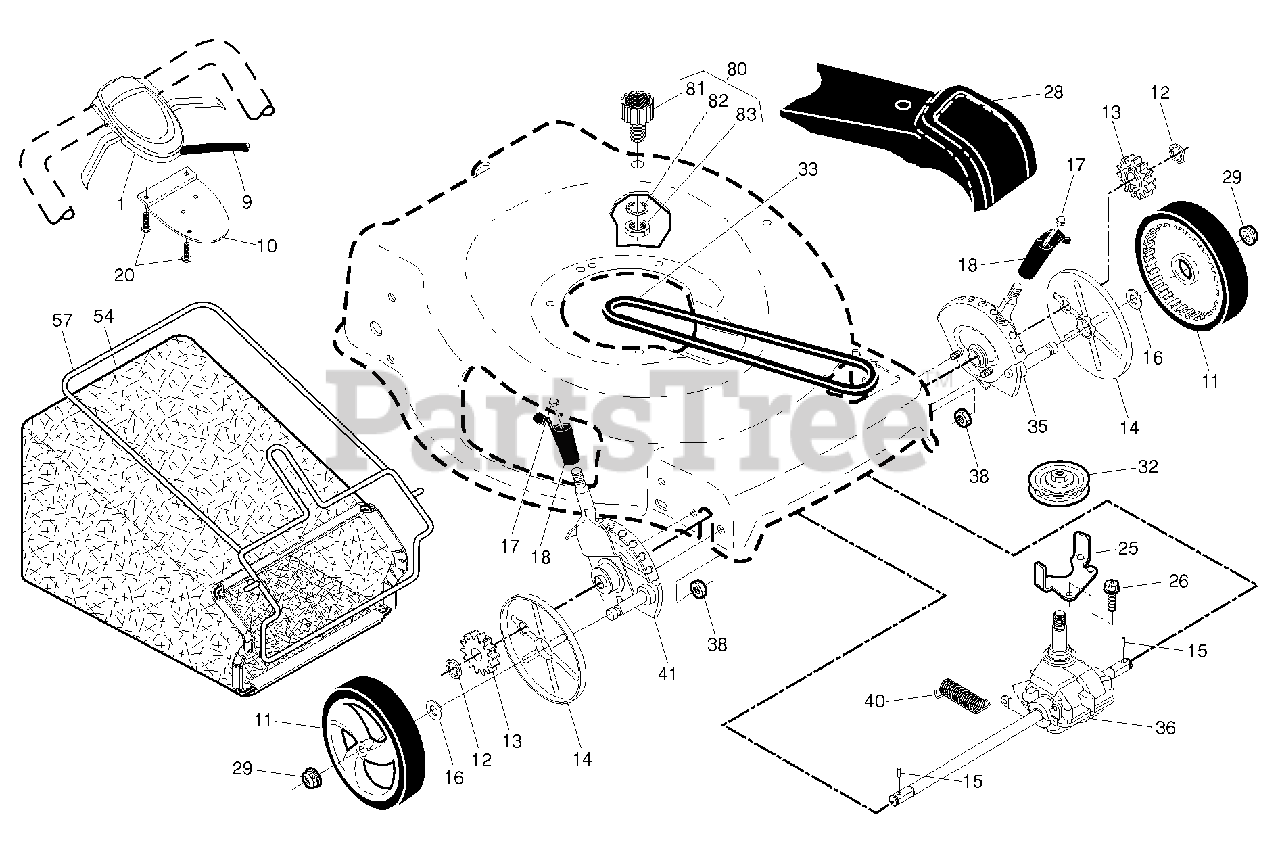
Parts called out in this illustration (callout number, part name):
1	Control, Aw2 22+Fg Gen Bs Bk/Bk
10	BRACKET.DRIVE.CONTR.GEN2.BLACK
12	E-RING 7/16 RE
13	PINION.14.TEETH.FGD
14	Inner Wheel Dust Cover
15	PAWL, DRIVE
16	WASHER FLUT
20	SCREW, PHILLIPS HEAD 10 X 5/8
25	BRACKET.BELT.GUIDE.22+FGD.BZP
28	Drive Cover Assembly, 419930 Ce
29	NUT.HEX.FLANGE.3/8-16.LOCKNUT
32	PULLEY.DRIVEN.EZ/VARI (2 2MC)
38	NUT.FLANGE.1-4-20-SERR
54	GBAG.A3610010.BLK.GENERIC
57	Grass Bag Frame, 22+ Black
80	KIT.WASH-OUT PORT.ZINC
81	WASHOUT.PORT.ZINC.RGD.22+
82	WASHER.LOCK.INTERNAL.TOOTH
83	LOCKNUT.HEX.WITH.O-RING
